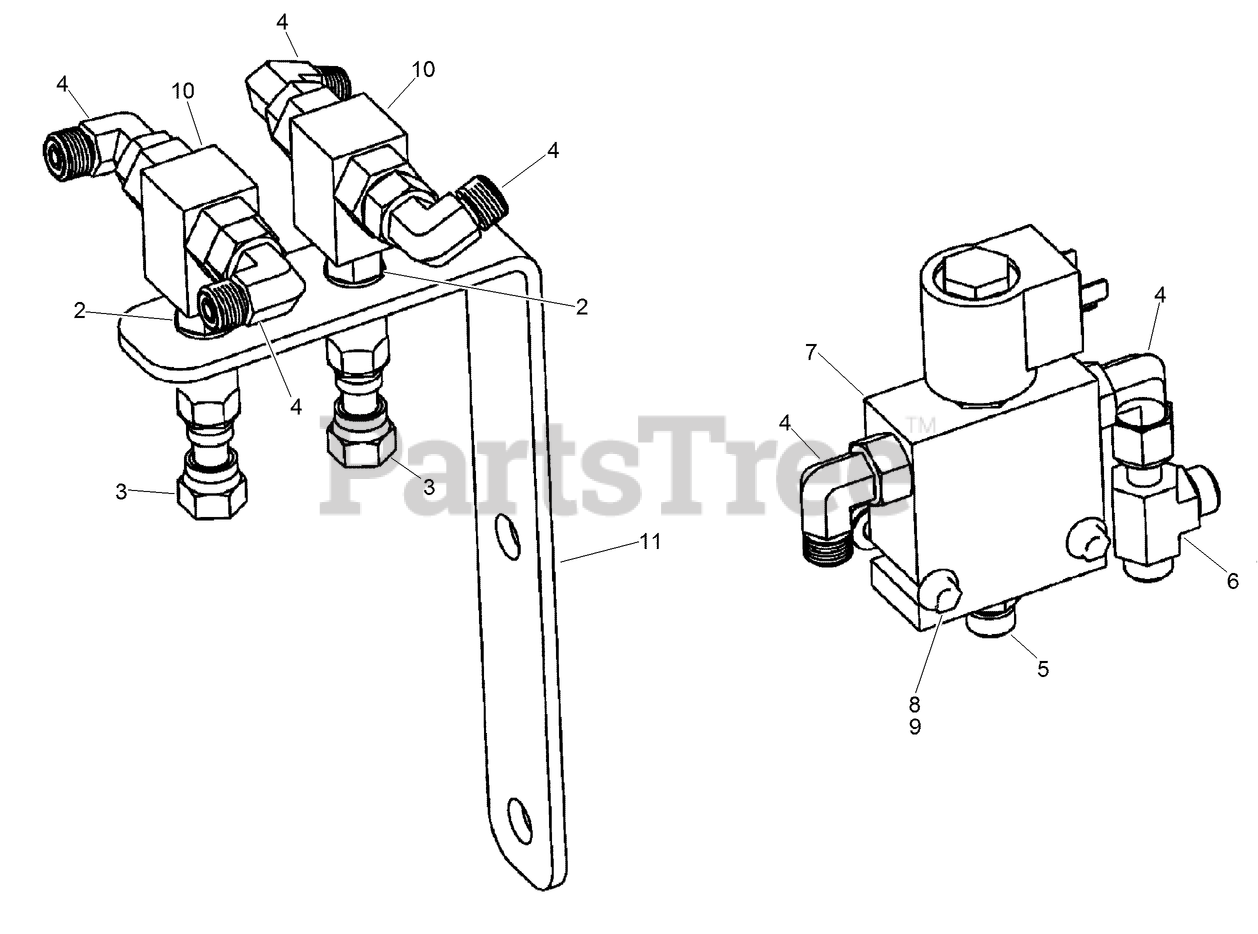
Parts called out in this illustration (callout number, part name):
2	FITTING-STRAIGHT
3	FITTING-STRAIGHT
4	CONNECTION - 90 Deg, -4 ORFS / -6 ORB
5	CONNECTION - Straight, -4 ORFS / -6 ORB
6	CONNECTION - Run Tee, -4 ORFS / -4 ORFS
7	VALVE - Dir, Cart, 3W2P, SOL, 12VDC
8	SCREW, METRIC FLANGE w/BODY - M6 x 50
9	NUT, METRIC FLANGE PREVAILING - M6 Zinc
10	VALVE-SHUTTLE, LOAD
11	PLATE - Mount, Shuttle Valve
